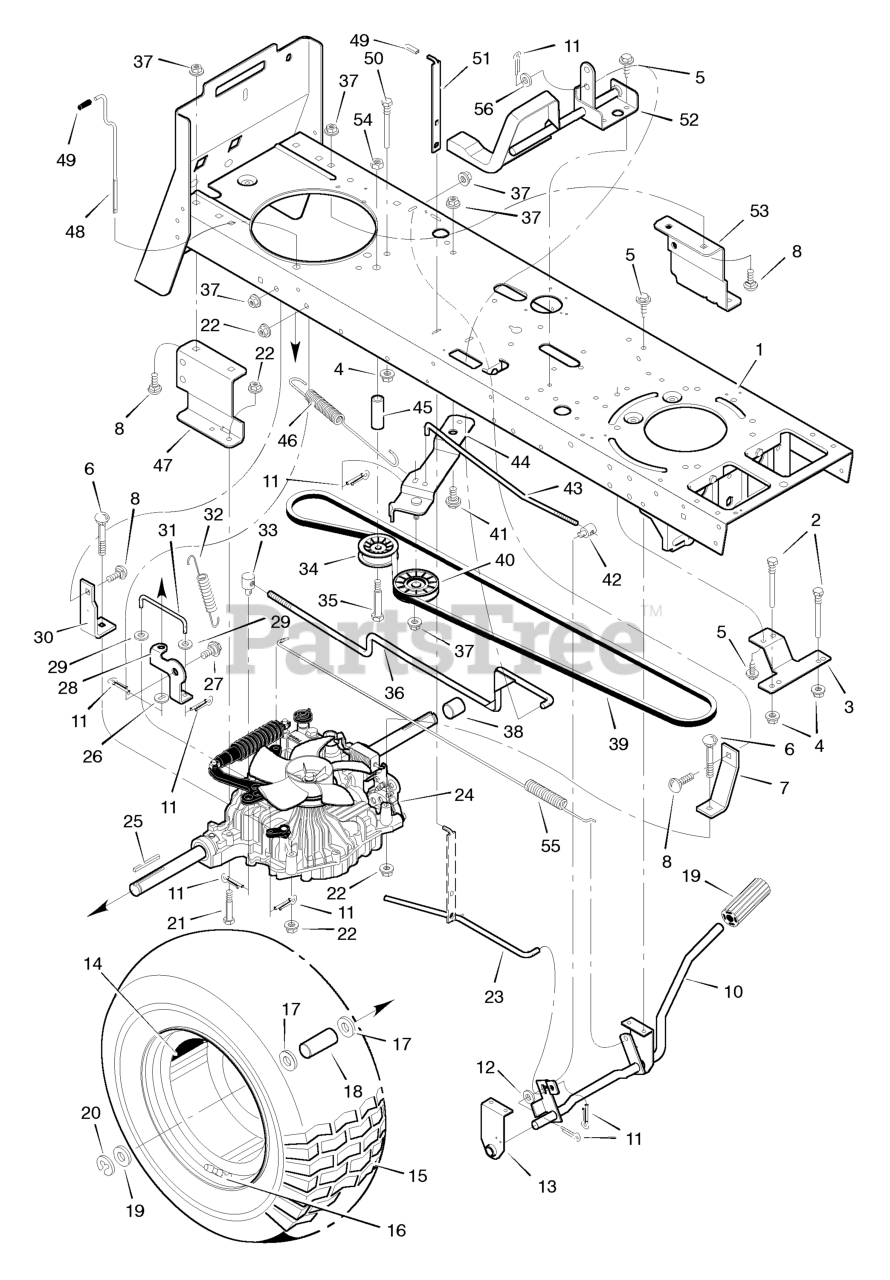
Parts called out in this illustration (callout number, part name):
1	Frame Assembly
2	Guide, Belt
3	Bracket, Belt Guide
4	Nut, Flange
6	Bolt, Carriage
7	Bracket, Torque
8	Bolt, Carriage
9	Pedal
10	Lever Assembly, Pedal
11	Pin, Cotter
12	Washer
13	Support, Pedal
14	Wheel and Tire Assembly
15	Tire *
16	Valve Stem
17	Washer
18	Spacer
19	WASHER, 1-1.3 16G FLT
21	Bolt, Hex
22	Nut
23	Rod, Latch
24	Transaxle
25	Key, Square
27	Bolt, Shoulder
28	Bracket, Dump Valve
29	Washer
30	Bracket, Torque
31	Rod, Dump Valve
32	Spring, Extension
33	NUT, Adjusting, 1/2-13
34	Pulley, Idler
35	Bolt, Hex
36	Rod, Control
37	Nut
38	Spacer
40	Pulley, Idler
41	Bolt, Shoulder
42	Nut, Adjusting
43	Rod, Clutch
44	Bracket, Idler
45	Spacer
46	Spring, Extension
47	Bracket, Right Transaxle
48	Rod, Dump Valve
50	Guide, Belt
51	Lever, Parking Brake
52	Pedal Assembly
53	Bracket, Left Transaxle
56	Washer
